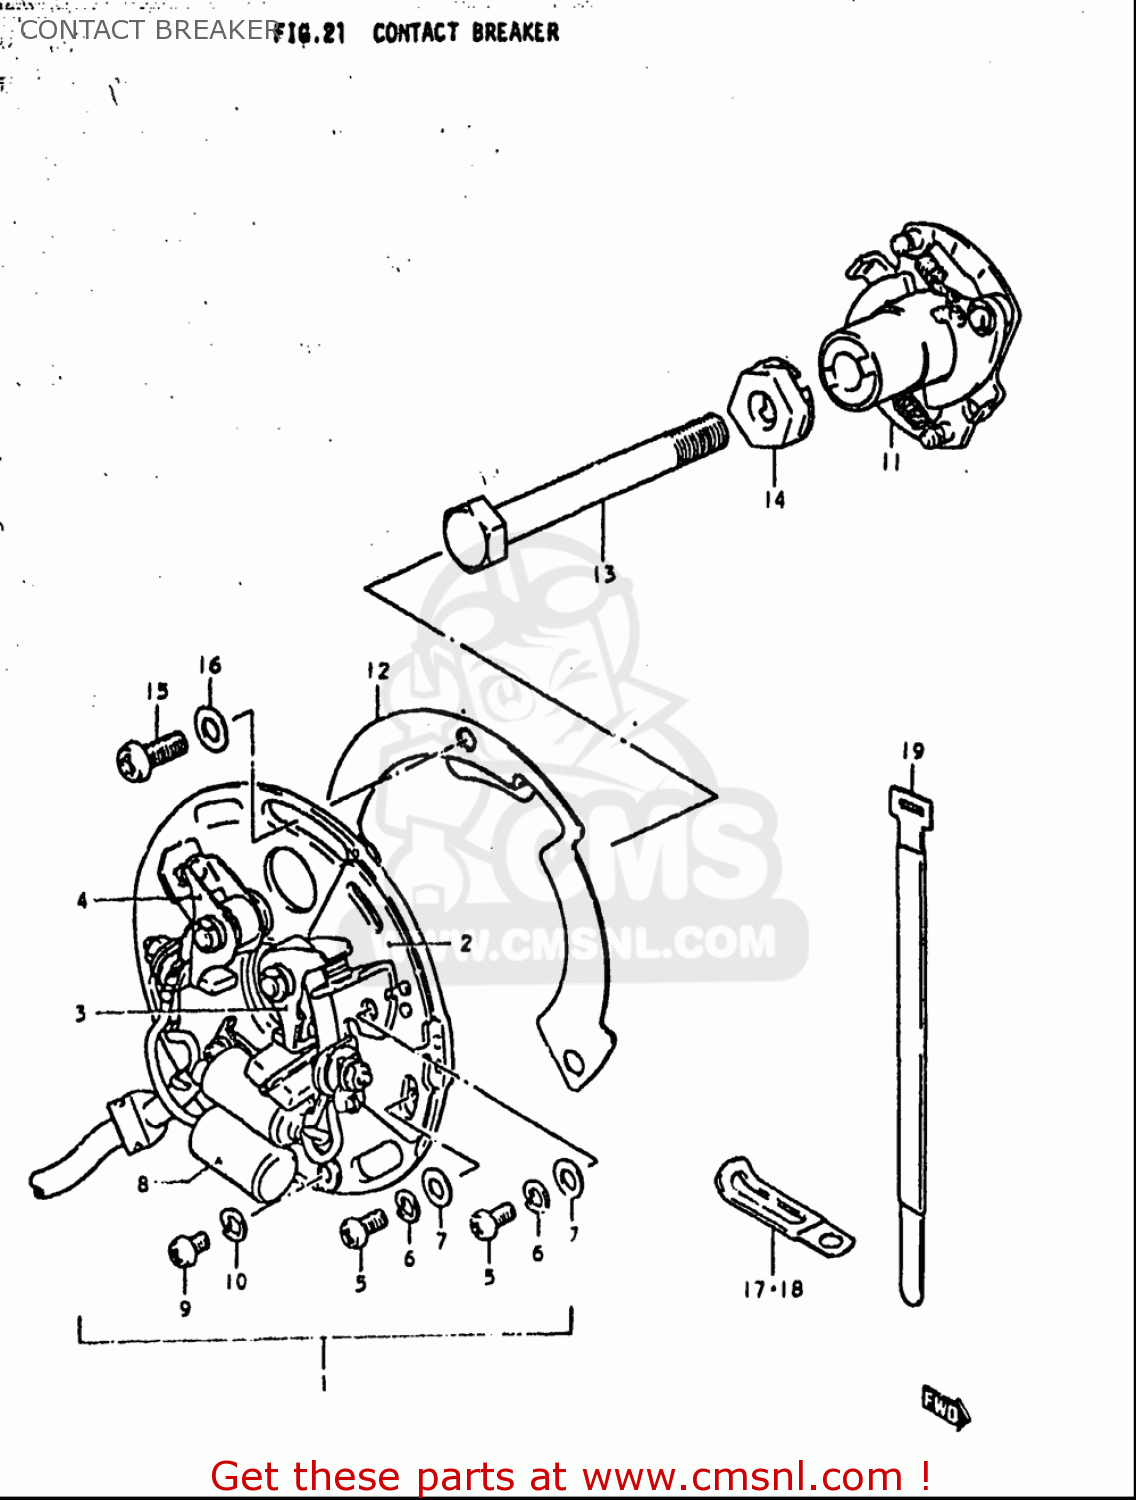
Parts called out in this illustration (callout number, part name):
1	BREAKER ASSEMBLY,CONTACT
2	PLATE,CONTACT POINT
3	POINT ASSY,R
4	POINT ASSY,L
5	SCREW(4X10)
6	WASHER,LOCK
7	WASHER
8	CONDENSER
9	SCREW 4X6
10	WASHER,LOCK
11	GOVERNOR ASSEMBLY
12	PLATE,IGNITION TIMING
13	BOLT
14	WASHER
15	SCREW(5X12)
16	WASHER
17	CLAMP(L:65)
18	CLAMP(L:120 T:1.0)
19	CLAMP
